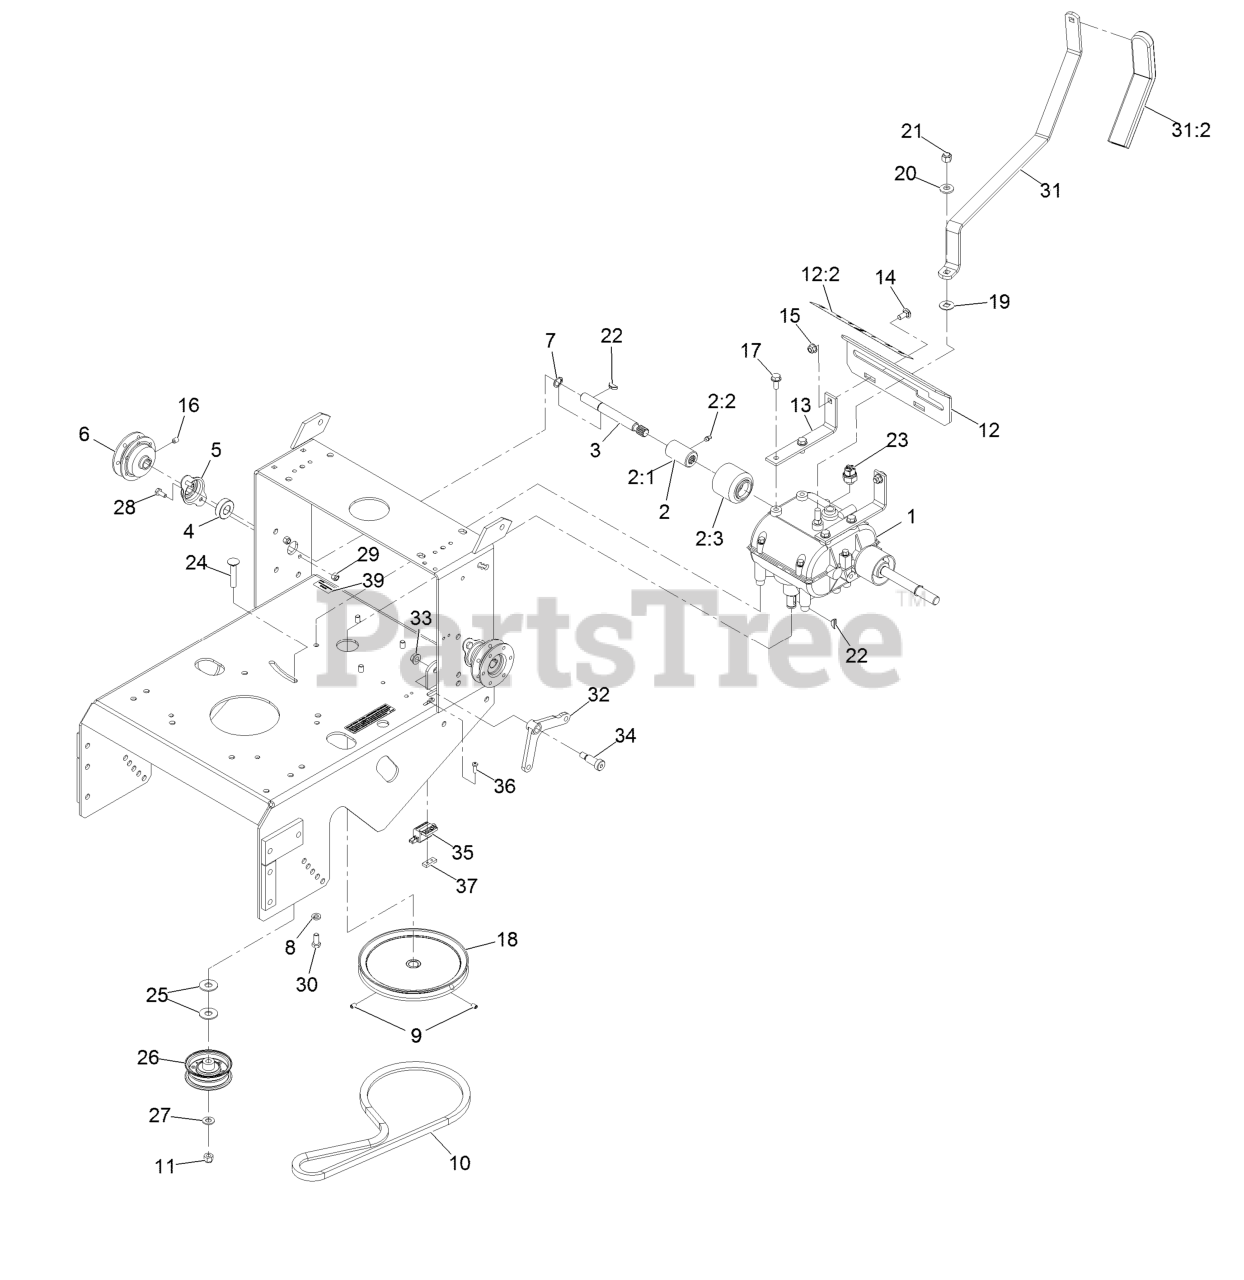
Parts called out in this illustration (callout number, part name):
1	Transmission-5 Speed
2	Coupling, W/Guard And Zerk
2:1	Coupler
2:2	Zerk-1/4-28 Str
2:3	Guard-Coupler
3	Shaft-Transmission
4	Bearing-Shaft
5	Flange-Output
6	Sheave-Transmission
7	Ring-Retaining
8	Washer-Lock 5/16 Heavy
9	Setscrew-1/4-20 X 3/8
10	Belt, Transmission Drive
11	Nut-Nyloc 3/8-16
12	Asm, Shifter Plate W/ Decals
12:2	Decal-Speed, Ground
13	Bracket-Plate, Shift
14	Bolt-Carriage 5/16-18 X 3/4
15	Nut-Nyloc 5/16-18 Flg
16	Setscrew-5/16-18 X 3/8
17	Screw-HWH 5/16-18 X 3/4 Tf
18	Sheave-Transmission
20	Washer-Spring Disc 3/8
21	Nut-Nyloc 3/8-24
22	Key-Woodruff #9 3/4 X 3/16
23	Switch-Start, Neutral
24	Bolt-Carriage 3/8-16 X 2
25	Washer-7/16 Std
26	Pulley-Idler, Flat
27	Washer-3/8 SAE
28	Screw-HH 1/4-20 X 5/8
29	Nut-Nyloc 1/4-20
30	Screw-HH 5/16-18 X 3/4
31	Lever, Shift W/Grip
31:2	Grip Foam
32	Bellcrank
33	Nut-Whizlock 3/8-16
34	Bolt-Shoulder
35	Switch-N.O.
36	Screw-PPH #10-24 X 5/8
37	Plate-Tapped
39	Decal-Patent
